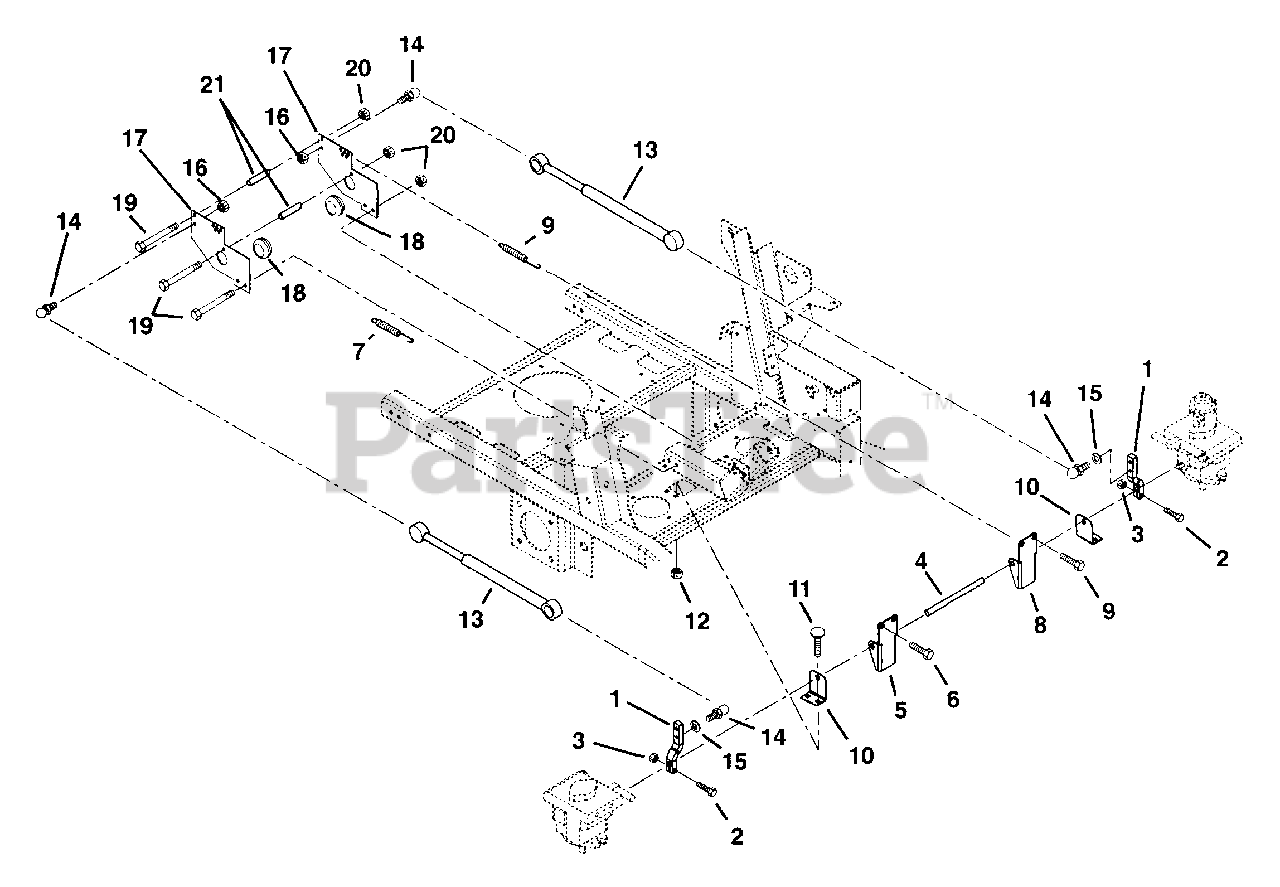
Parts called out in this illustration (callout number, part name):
1	Arm-Pump Actuating
2	Bolt-Hex .25-20 x 1.25 Grade 5
3	Nut-Locking-Center .25-20
4	Rod-Pivot
5	Pivot-Neutral Right-Hand
6	Bolt-Hex .31-18 x 1.00 Grade 5
7	Spring-Tension .085 x .60 x 5.13
8	Pivot-Neutral Left-Hand
9	Spring-Tension .085 x .60 x 5.13
10	Support-Pivot Rod
11	Bolt-Round Head Square Neck .31-18 x .75
12	Nut-Locking-Nylon .312-18
13	Dampener Control
14	Stud-Ball
15	Washer-Locking .31 x .078
16	Nut-Locking-Center .31-18
17	Anchor-Damper
18	Grommet .125 x 1.000
19	Bolt-Hex .31-18 x 2.75 Grade 5
20	Nut-Locking-Center .31-18
